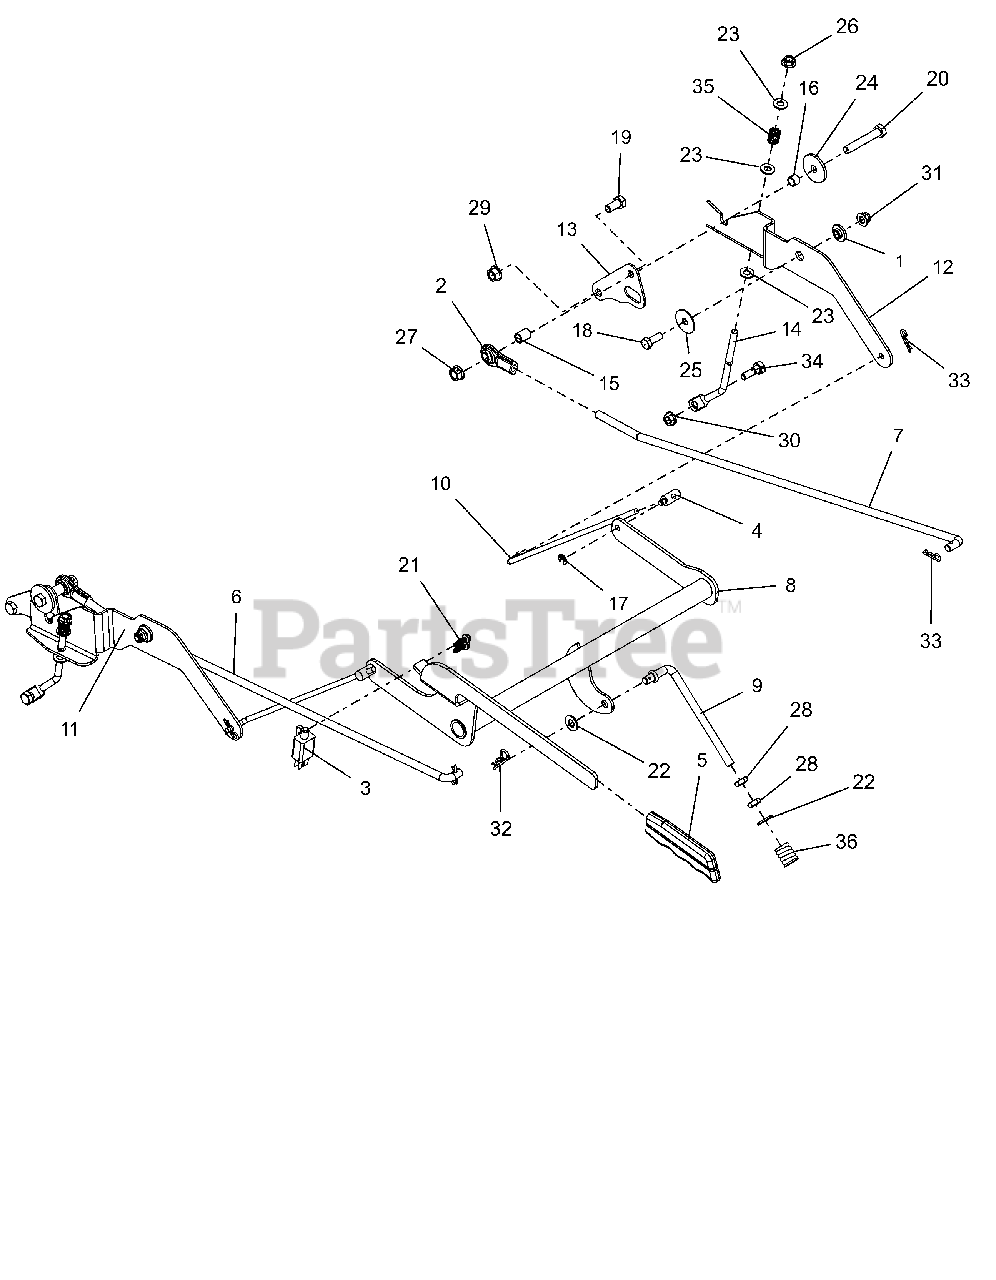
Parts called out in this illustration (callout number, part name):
1	BSHG, FLG .325X.499X.26X.88
2	ROD END, .38 RH
3	SWITCH- DOUBLE POLE N.O./N.O.
4	TRUNION, 1/4-20
5	GRIP, PARKING BRAKE (YELLOW)
6	STEERING, LINKAGE RH
7	STEERING, LINKAGE LH
8	WLDMT, BRAKE LEVER
9	LINK, OVER CENTER, PARKING BRK
10	ROD, PARK BRAKE
11	INTERLOCK, RH BRAKE LINK
12	INTERLOCK, LH BRAKE LINK
13	PLATE, TRANSAXLE ADAPTOR
14	LINK, TRANSAXLE BRAKE
15	SPCR, SLV .385X.500X.652
16	SPCR, SLV .385X.500X.350
17	RG-RTNG-EXT .250X.025
18	BOLT-HEX.31-18X.875 YWZC GR5
19	@BLT-HEX .38-16X.75 GR5 YWZC
20	@BLT-HEX .38-16X2.25 GR5 YWZC
21	SCR-TAP #12X.75 BOSS INDHXHD
22	@WSHR-FL-STL.406X.812X.065 YWZ
23	@WSHR-FL-STL.344X.688X.065YWZC
24	WSHR-FL-STL .380X1.50X.125YWZC
25	WSHR-FL-STL .347X1.254X.048YWZ
26	@NUT-LK-CTR-FLG .31-18 YZ GR F
27	NUT-LK-CTR-FLG .38-16 YWZC
28	NUT-HEX-JAM .375-16 YWZC
29	@NUT-LK-TOP-FLG .38-16 YWZC
30	@NUT-LK-TOP-FLG .31-18 YWZC
31	@NUT-LK-NYL-FLG .31-18 YWZC
32	PIN-HAIR CTR .09 X 1.50 YWZC
33	PIN-HAIR INT .08X.18X1.18 YWZC
34	BOLT,SHLDR .38X.25 -.31-18X.75
35	SPRING, COMPRESSION
36	SG-COMP .187X.56X1.62
